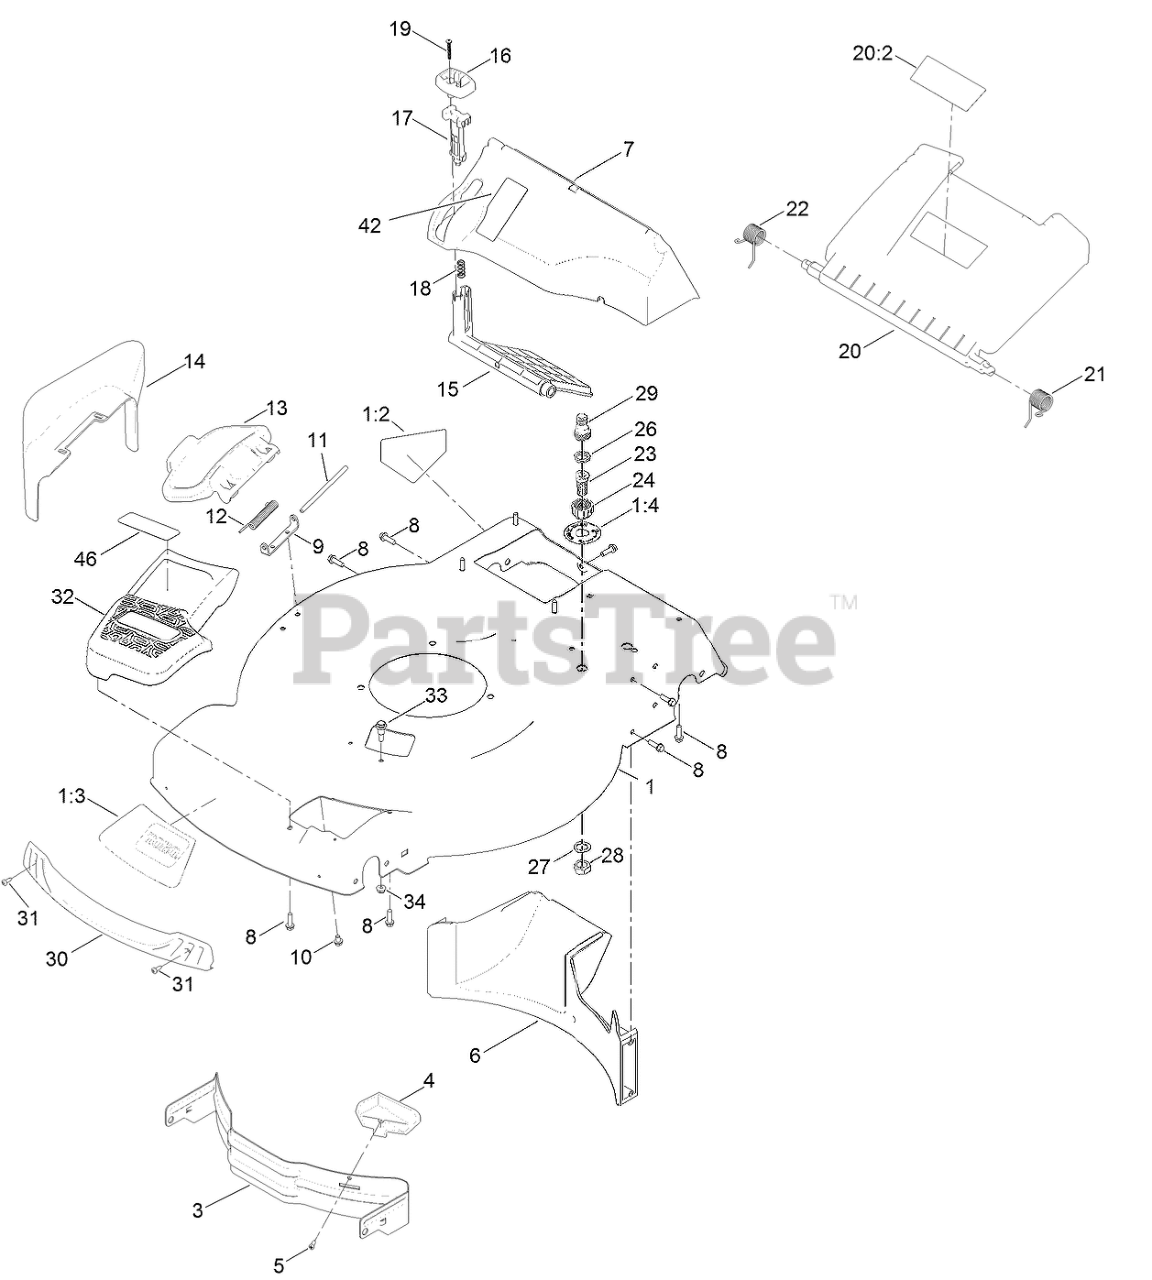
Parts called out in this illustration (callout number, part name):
1	HOUSING ASM
1:2	DECAL-DANGER
1:3	DECAL-DECK
1:4	DECAL-PORT, WASHOUT
3	BAFFLE-FRONT
4	KICKER-FRONT
5	SCREW-PPH
6	BAFFLE-REAR
7	CHUTE-RECYCLE
8	SCREW-HWH
9	BRACKET-COVER
10	SCREW-HWH
11	ROD-COVER
12	SPRING-TORSION
13	DEFLECTOR-SIDE
14	CHUTE-DISCHARGE, SIDE
15	DEFLECTOR-RECYCLE
16	KNOB-RECYCLE
17	LATCH-RECYCLE
18	SPRING-COMPRESSION
19	SCREW-PPH
20	REAR DOOR ASM
20:2	DECAL-WARNING
21	SPRING-TORSION
22	SPRING-TORSION
23	PORT-WASHOUT
24	COUPLING-HOSE, WASHOUT PORT
26	WASHER-SEAL, WASHOUT PORT
27	WASHER-TOOTH, INTERNAL
28	NUT-JAM
29	ADAPTER-CONNECT, QUICK
30	BUMPER
31	SCREW-FORMING, THREAD
32	COVER-BELT, FRONT
33	BOLT-SHOULDER
34	NUT-LOCK, NI
46	DECAL-COVER
